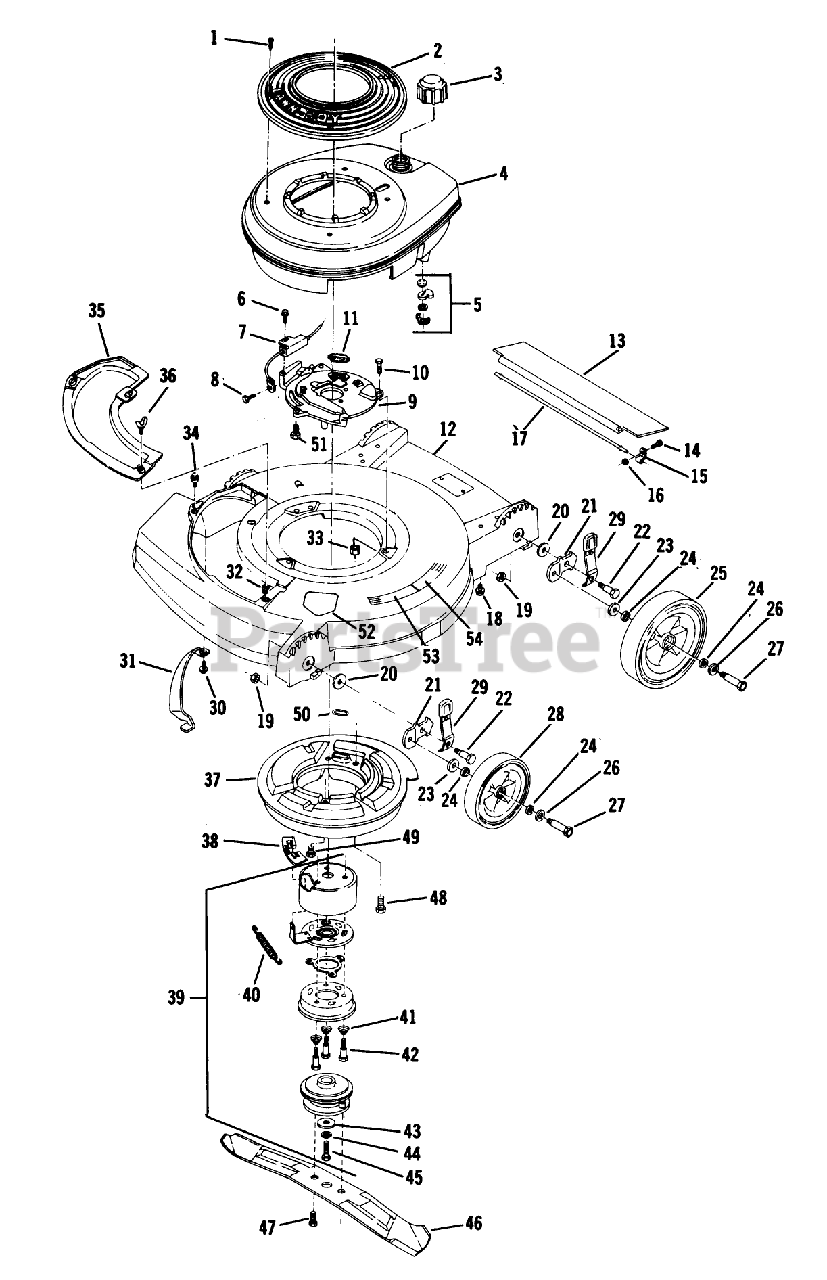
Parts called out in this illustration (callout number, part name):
1	SCREW - SELF TAPPING
3	FUEL CAP & INSERT
5	SHUT OFF VALVE KIT
6	SCREW
7	CONTROL CABLE
10	SCREW
15	CLAMP ROD KMC
16	LOCKNUT E
17	ROD 21" ADVANCE
18	SCREW
19	LOCKNUT
20	WASHER
23	WASHER WROUGHT
24	WASHER
26	SPACER
27	BOLT WHEEL
28	WHEEL & TIRE KIT
31	BAR-TOE
33	NUT-LOCK F
36	WING SCREW LAWRE
40	SPRING
42	SCREW,SHOULDER SM
43	WASHER
47	SCREW SEMS
49	SCREW
50	SEAL
51	SCREW V
53	PAD FOOT
